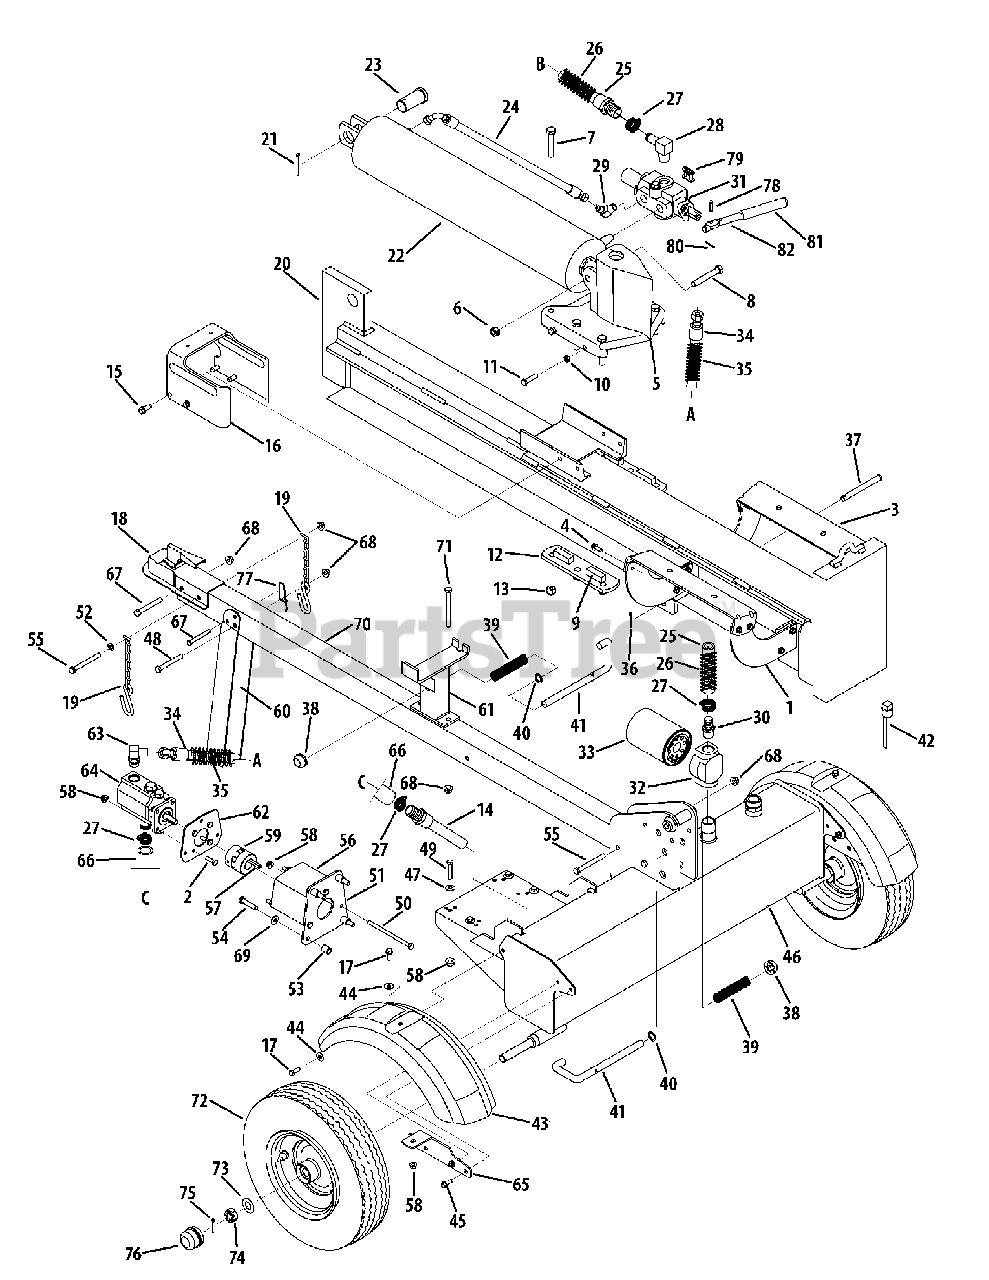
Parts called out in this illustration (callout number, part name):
2	Hex Screw, 5/16-18 x 1.00
4	Self-Tapping Screw, 5/16-18 x .750
5	Wedge Assembly
6	Lock Nut, 1/2-13
7	Hex Cap Screw, 1/2-20 x 2.75
8	Hex Cap Screw, 1/2-13 x 3.25
9	Adjustable Gib
10	Hex Jam Nut, 3/8 -24
11	Hex Cap Screw, 3/8 -24 x 1.5
13	Hex Lock Nut, 1/2-20
14	Inlet Filter
15	Hex Washer Screw, 3/8 -16 x 1.0
17	Self-Tapping Screw, 5/16-18 x .875
18	Hitch Coupler, 2"
20	Beam Assembly
21	Cotter Pin
22	Hydraulic Cylinder,
22	Kit Seal 5.0" for XINGHUI cylinder
22	Kit Seal 5.0" for ENERGY cylinder
23	Clevis Pin
24	Hydraulic Hose
25	Return Hose, 3/4" ID x 44"
26	Hose Guard
27	Hose Clamp, 5/8 "
28	Return Elbow
29	90 Degree Solid Male Adapter
30	3/4" Hose Adapter
31	Control Valve
32	Filter Housing
33	Oil Filter
34	High Pressure Hydraulic Hose
35	Hose Guard
36	Cotter Pin, 1/8 "
37	Hinge Pin, 1/2 x 4.8" Lg.
39	Compression Spring, 4"
40	Flat Washer, .635 ID x .93 OD
41	Locking Rod
42	Vented Dipstick
44	Flat Washer, .343 x .880 x .062
45	Self-tap Screw, 5/16-18 x 1.00
46	Frame Assembly, 7.0 Gal
47	Bell Washer, 340 x .872 x .060
48	Hex Cap Screw, 3/8 -16 x 3.00
49	Hex Cap Screw, 5/16-18 x 1.75
50	Hex Cap Screw, 5/16-18 x 5.50
53	Spacer, .385 x .623 x .750
54	Hex Cap Screw, 3/8 -16 x 1.75
55	Hex Cap Screw, 3/8 -16 x 3.50
56	Coupling Shield
57	Key
58	Hex Flange Lock Nut, 5/16-18
59	Coupling, .500
59	Coupling, .875
63	Adapter, 7/8-14
64	Pump
66	Suction Hose
67	Clevis Pin, 5/16 x 2.5
68	Flange Lock Nut, 3/8 -16
69	Lock Washer, 3/8
71	Hex Cap Screw, 3/8 -16 x 4.0
72	Wheel Assembly
73	Flat Washer, .76" ID x 1.5" OD
74	Slotted Nut, 3/4-16
75	Cotter Pin, 5/32" x 1-1/4"
77	Spring Pin
78	Clevis Pin
79	Valve Handle Link
80	Cotter Pin
82	Hydraulic Valve Control
